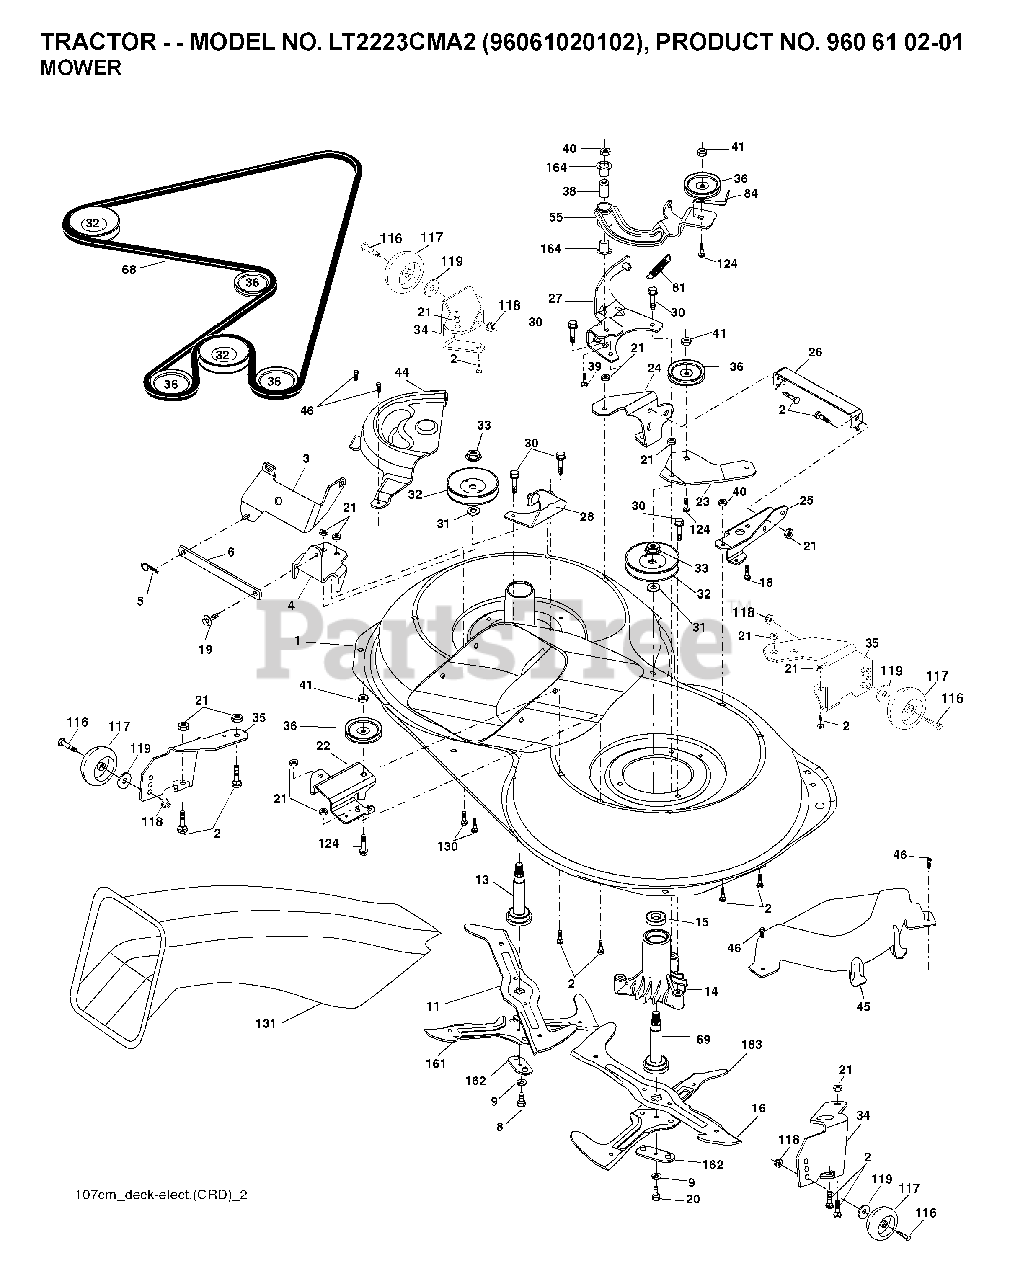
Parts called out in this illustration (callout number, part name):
2	BOLT
3	BRACKET
5	RETAINER-SPRNG RB
6	BAR SWAY
9	LOCKWASHER
11	BLADE.3N1.LH.CRD
13	SHAFT ASM VENT
14	HSG MANDREL
16	BLADE.3N1.RH.CRD
19	BOLT SHD 5/16-18
21	LOCKNUT
22	BRACKET
23	BRACKET
27	BRACKET
30	SCREW, WASHER HEAD
31	WASHER.SPACER.MANDREL
33	NUT.FLANGE.LOCK.TOP
36	PULLEY.IDLER.4.25
40	LOCKNUT
41	NUT LOCK FLG 3/8-16 UNC
45	MANDREL COVER
46	SCREW.1/4-20X5/8
55	ARM IDLER
68	HEX-BELT 107 MOWER
69	SHAFT.ASM.W/LWR.BRG.RH.THREAD
84	KEEPER, BELT IDLER
116	BOLT.SHOULDER.3/8-16X3-5/8
117	WHEEL. GUAGE RALLY
118	NUT LOCK FLG 3/8-16 UNC
124	BOLT.3/8-16X1.50
131	CHUTE BAGGER
164	BRNG T
